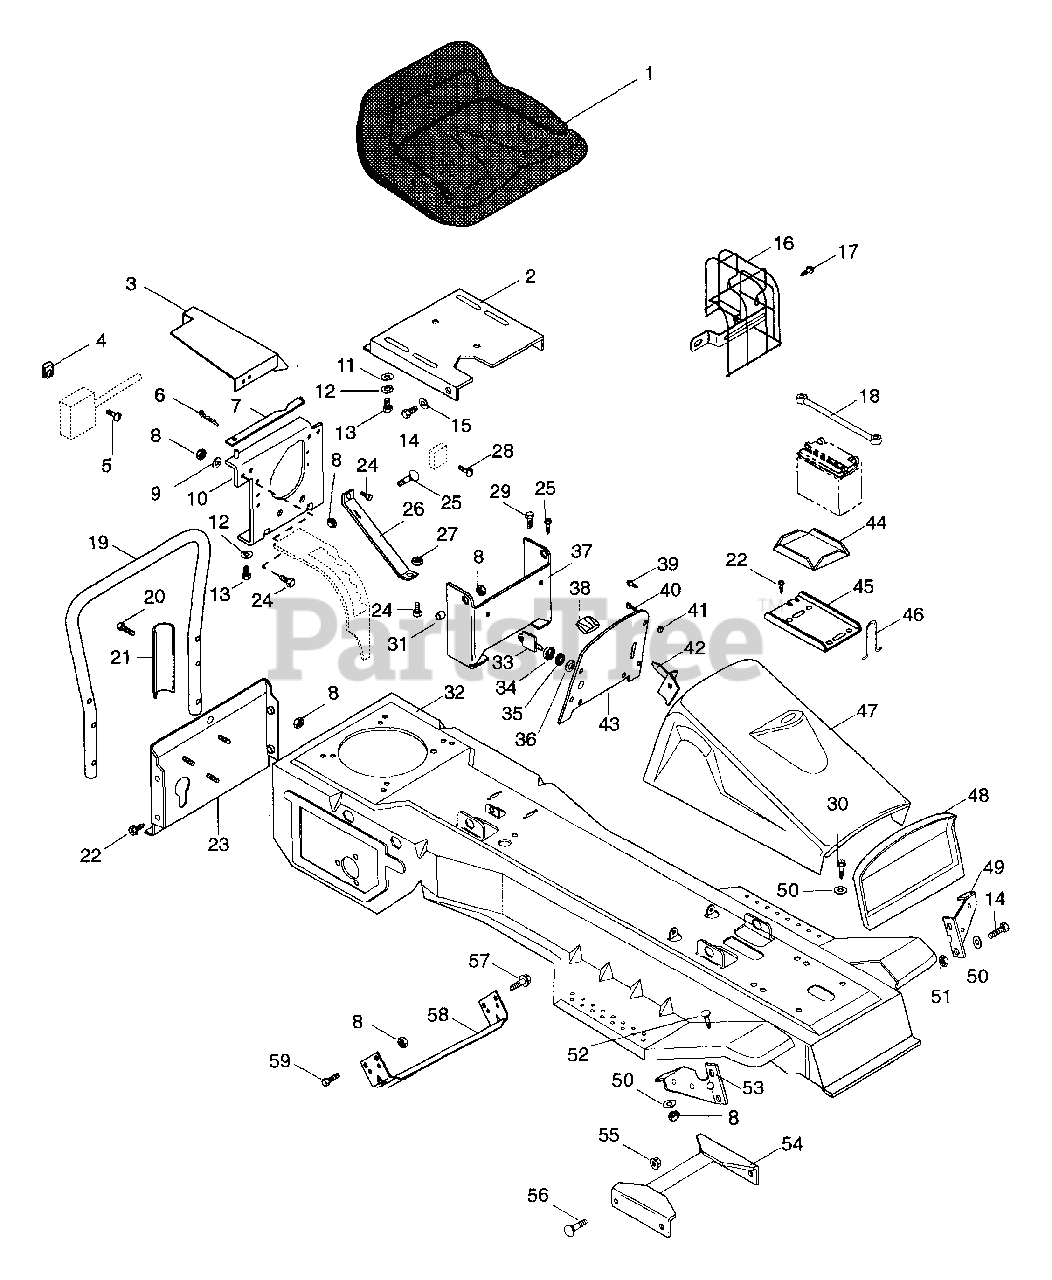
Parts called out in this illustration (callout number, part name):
1	SEAT- V1400
2	SEAT BRACKET
3	BAFFLE
4	NUT-KEPS 10-24 PL
5	SCR-MCH 10-24X.38 SLTOR PAN PL
6	PIN-HAIR INT .08X.18X1.18
7	SEAT HOLD DOWN
8	NUT-LK .312-18 GR A PL
9	WSHR-LK-INT .313X.030 PL
10	SEAT LEG ASSEMBLY
11	WSHR-FL-STL .38X.875X.083 PL
12	WSHR-LK .312X.097 PL HVY
13	BLT-HEX .31-18X.75 PL GR5
14	BLT-HEX .31-18X.75 PL GR2
15	WSHR-FL-STL .344X1.125X.063PL
16	MUFFLER GUARD (B&S#495945)
17	SCREW (B&S#094887)
18	BATTERY STRAP
19	TUBE
20	BLT-HEX .31-18X1.50 PL GR2
21	BRACE
22	SCR-TAP .312-18X.50 HWH PL TR
23	BACK COVER
24	BLT-HEX .25-20X.50 PL GR2
25	BLT-RDHDSQNK .312-18X.62 PL
27	NUT-LK-CTR .250-20 PL
28	SCR-MCH 10-24X.62 SLRH PL
29	BLT-HEX .31-18X.50 PL GR2
30	SCR-TAP .250-20X.50 HXSLHDPL
31	SPACER BUSHING .5 X .32 X .163
32	FRAME WITH DECALS
33	KEY SET
34	CAP - IGNITION SWITCH
35	NUT-PANEL .625-32 GRECO
36	WSHR-LK-INT .625X.045 PL
37	SEAT PIVOT BRACKET
39	SCR-TAP 10-12X.50 CRPH PL A BL
40	SCR-TAP 10-24X.375 CRPH 1A
41	PLASTIC GROMMET
42	THROTTLE CONTROL
43	DASH PANEL-RM
44	RUBBER PAD
45	BATTERY TRAY
46	HOOK
48	GRILLE INSERT & SHELL ASSEMBLY
49	L H FENDER BRACE
50	WSHR-FL-STL .323X.625X.062 PL
51	NUT-LK-TWIN .312-18 PL
52	BLT-RDHDSQNK .31-18X.75 GR5 PL
53	RH FENDER BRACE
54	FRAME BRACE
55	NUT-FLG. .312-18 PL
56	BLT-RDHDSQNK .312-18X.62SHTPL
57	SCR-TAP .312-18X1.50 HWH PL TR
58	FRAME BRACE
59	BLT-HEX .31-18X.63 PL GR 2
